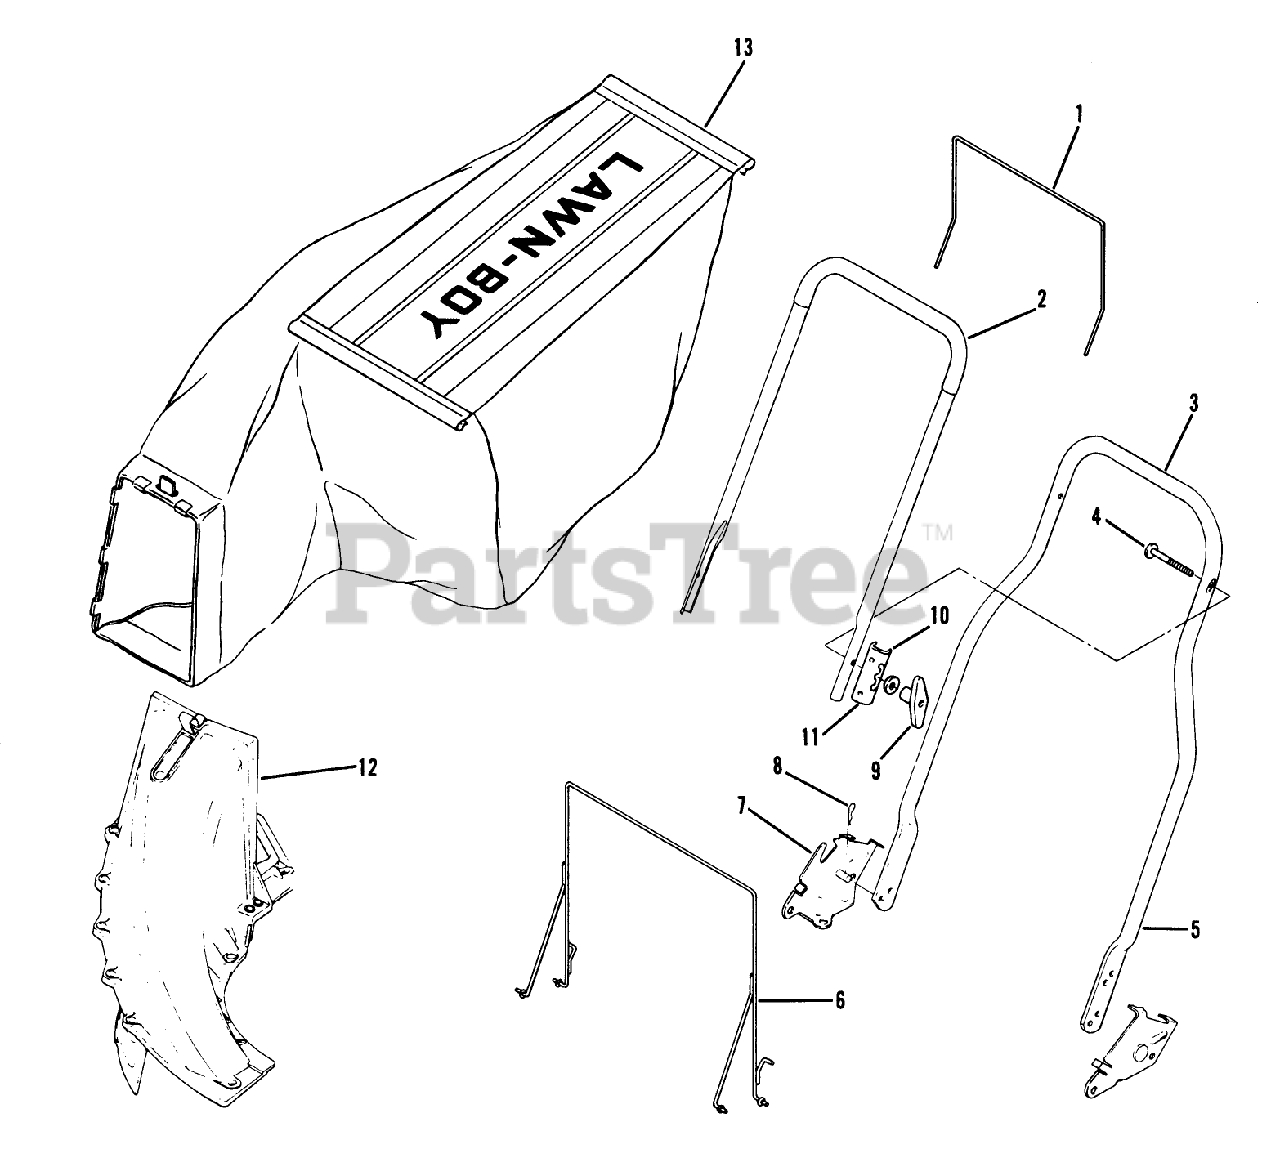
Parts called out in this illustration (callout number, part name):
8	HAIR PIN
9	NUT-WING
10	WASHER-CURVED
11	BRACKET R/B 613462
